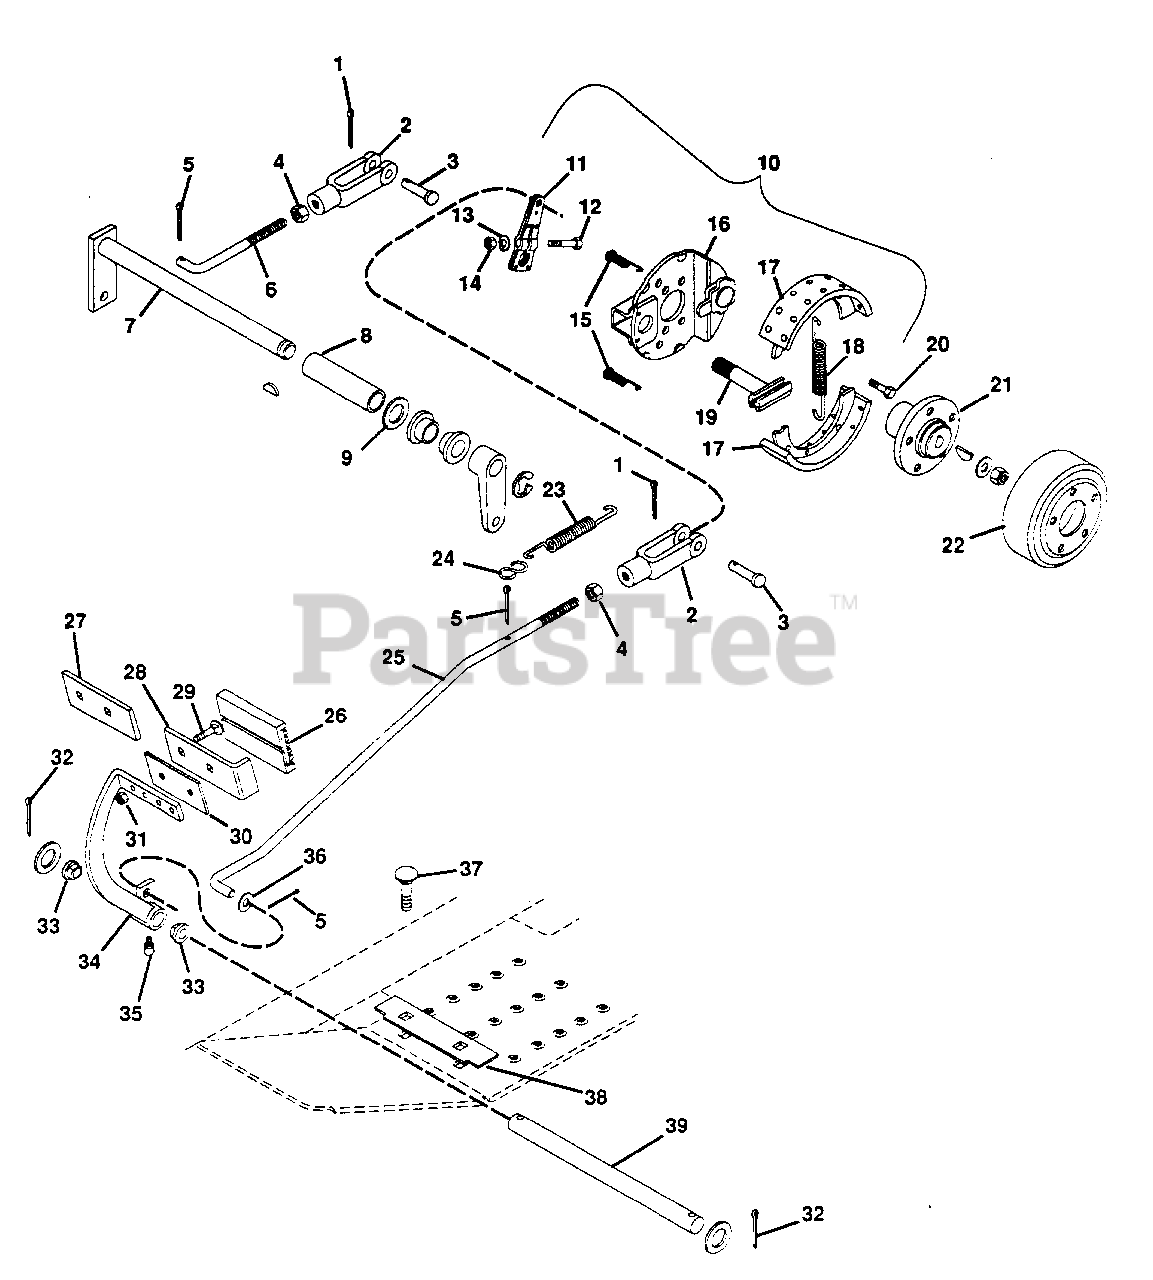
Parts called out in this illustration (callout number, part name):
1	Pin, Cotter .09x.75
2	Clevis, 3/8-24 Adjustable
3	Pin, Clevis .375x.948
4	Nut, Jam 3/8-24
5	Pin, Cotter .125x.75
6	Rod, Brake Control R.H.
7	Weldment, Brake Cross Shaft
8	Tube
9	Washer, Flat .813x1.37x.100
10	Brake, 7x1.75 Mechanical
11	Arm, Cam Lever
12	Bolt, Hex 5/16-24x1.75
13	Washer, Lock 5/16
14	Nut, Hex 5/16-24
15	Spring, Shoe Retaining
16	Plate, Back
17	Shoe, Brake
18	Spring, Shoe Return
19	Cam, Brake
20	Bolt, Hex 1/2-13x3.50
21	Hub, Wheel Tapered(Brake)
22	Drum, Brake
23	Spring, Ext. 5.5x.5x20 Rate
24	Clip, Spring
25	Rod, Brake Control L.H.
26	Pad, Pedal
27	Pedal, Brake
28	Pedal, Brake
29	Bolt, Carriage 1/4-20x1.25
30	Plate, Brake
31	Nut, Lock 1/4-20
32	Pin, Cotter .125x1.25
33	Bearing
34	Weldment, Brake Pedal L.H.
35	Fitting, Lube 1/4-28
36	Washer, Flat .406x.812x.065
37	Bolt, 3/8-16x1.00 Rd Hd Sq Nk
38	Strap, Brake Pedal Stop
39	Shaft, Brake Pedal Mntg
